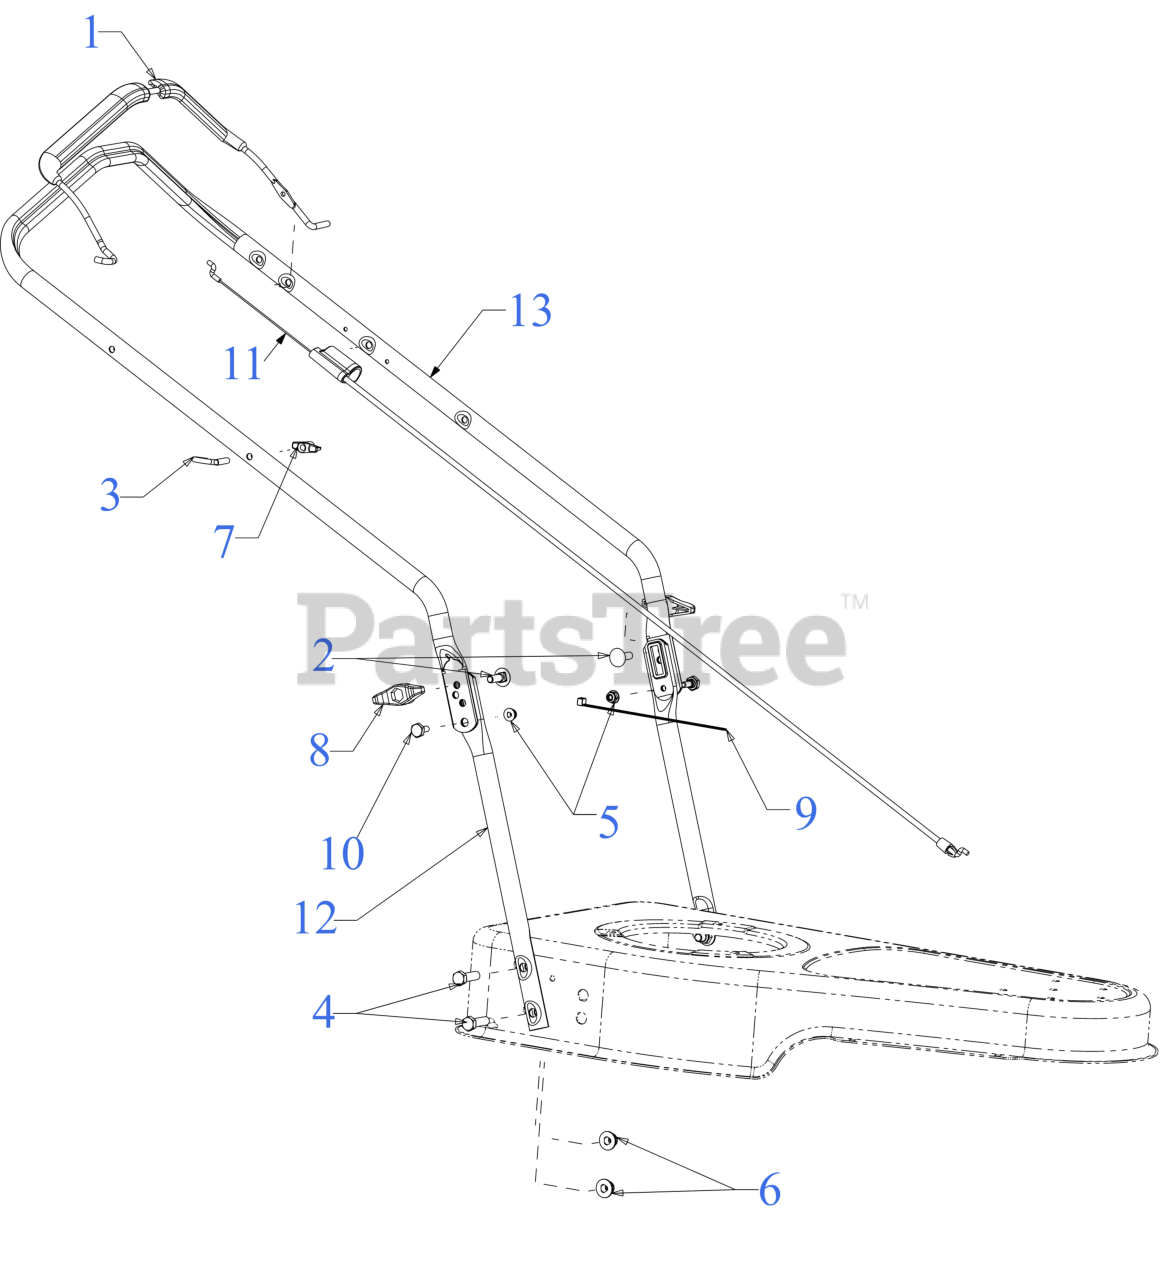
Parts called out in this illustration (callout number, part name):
1	OPERATOR BAIL ASSEMBLY
2	SCREW 5/16-18 x 1.00 GR5
3	EYEBOLT 1/4-20
4	SCREW 3/8-16 x 1.25 GR5
5	FLANGE LOCK NUT
7	HANDLE KNOB
8	WING KNOB 5/16-18
9	7" CABLE TIE
10	SHOULDER SCREW
11	CONTROL CABLE 37.58"
11	ERS CONTROL CABLE 49.7"
12	LOWER HANDLE (ADJUSTABLE)
13	UPPER HANDLE
